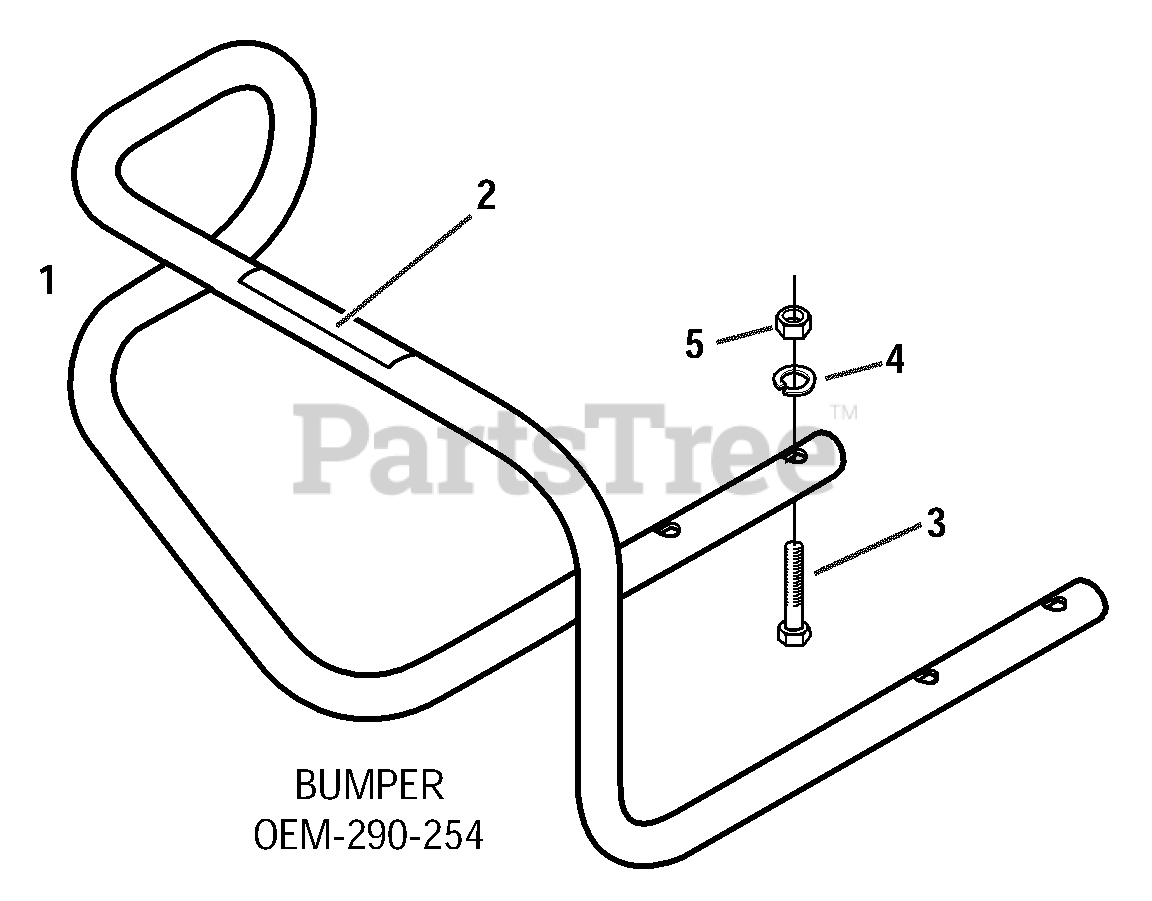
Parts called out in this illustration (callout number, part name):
2	Decal - Caution
3	Screw-hex hd., 5/16-18 x 2-1/4
4	Lockwasher-5/16
5	Nut-hex, 5/16-18
